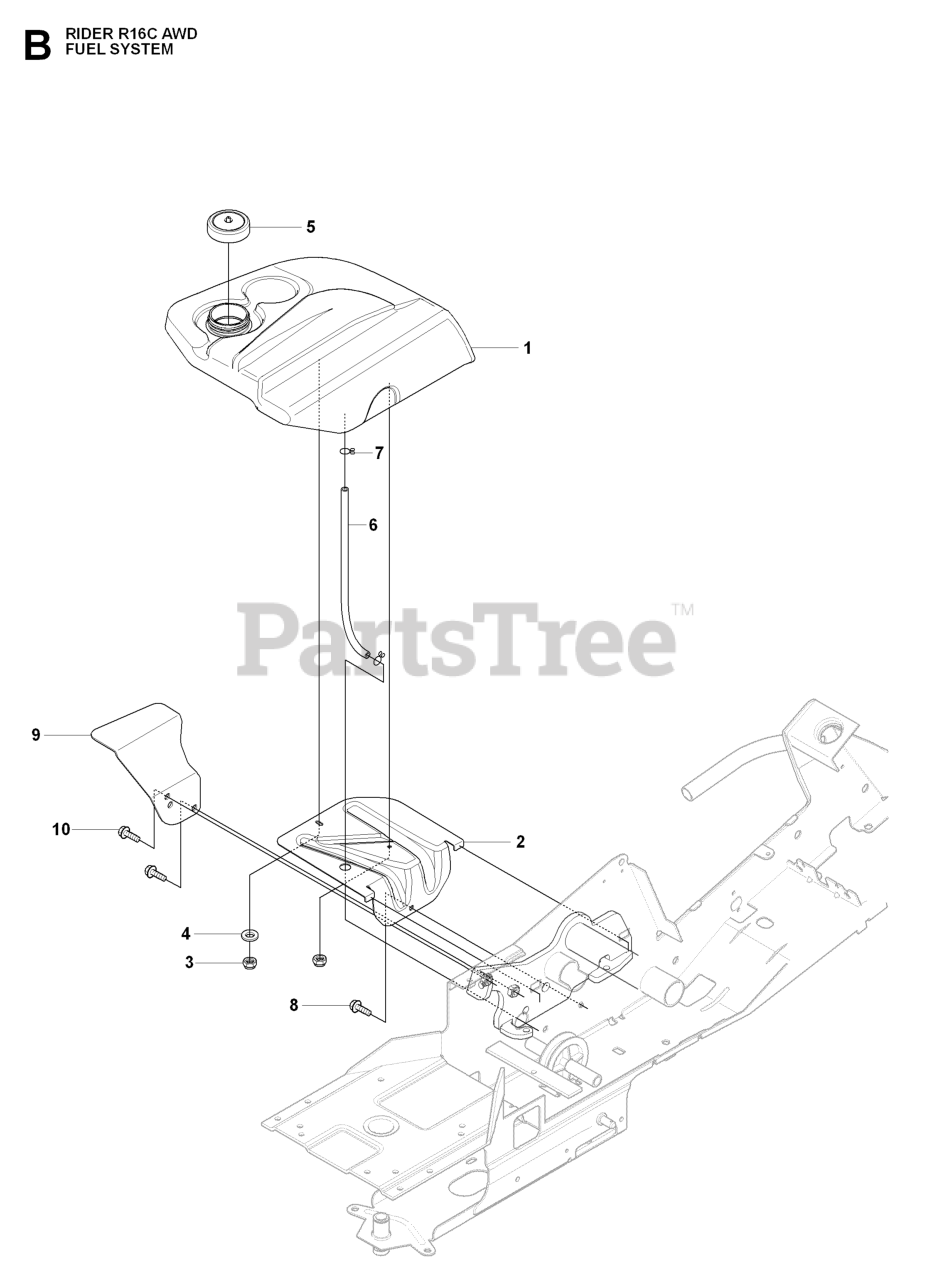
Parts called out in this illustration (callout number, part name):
3	LOCKNUT M6
4	WASHER
10	Screw M10x25
